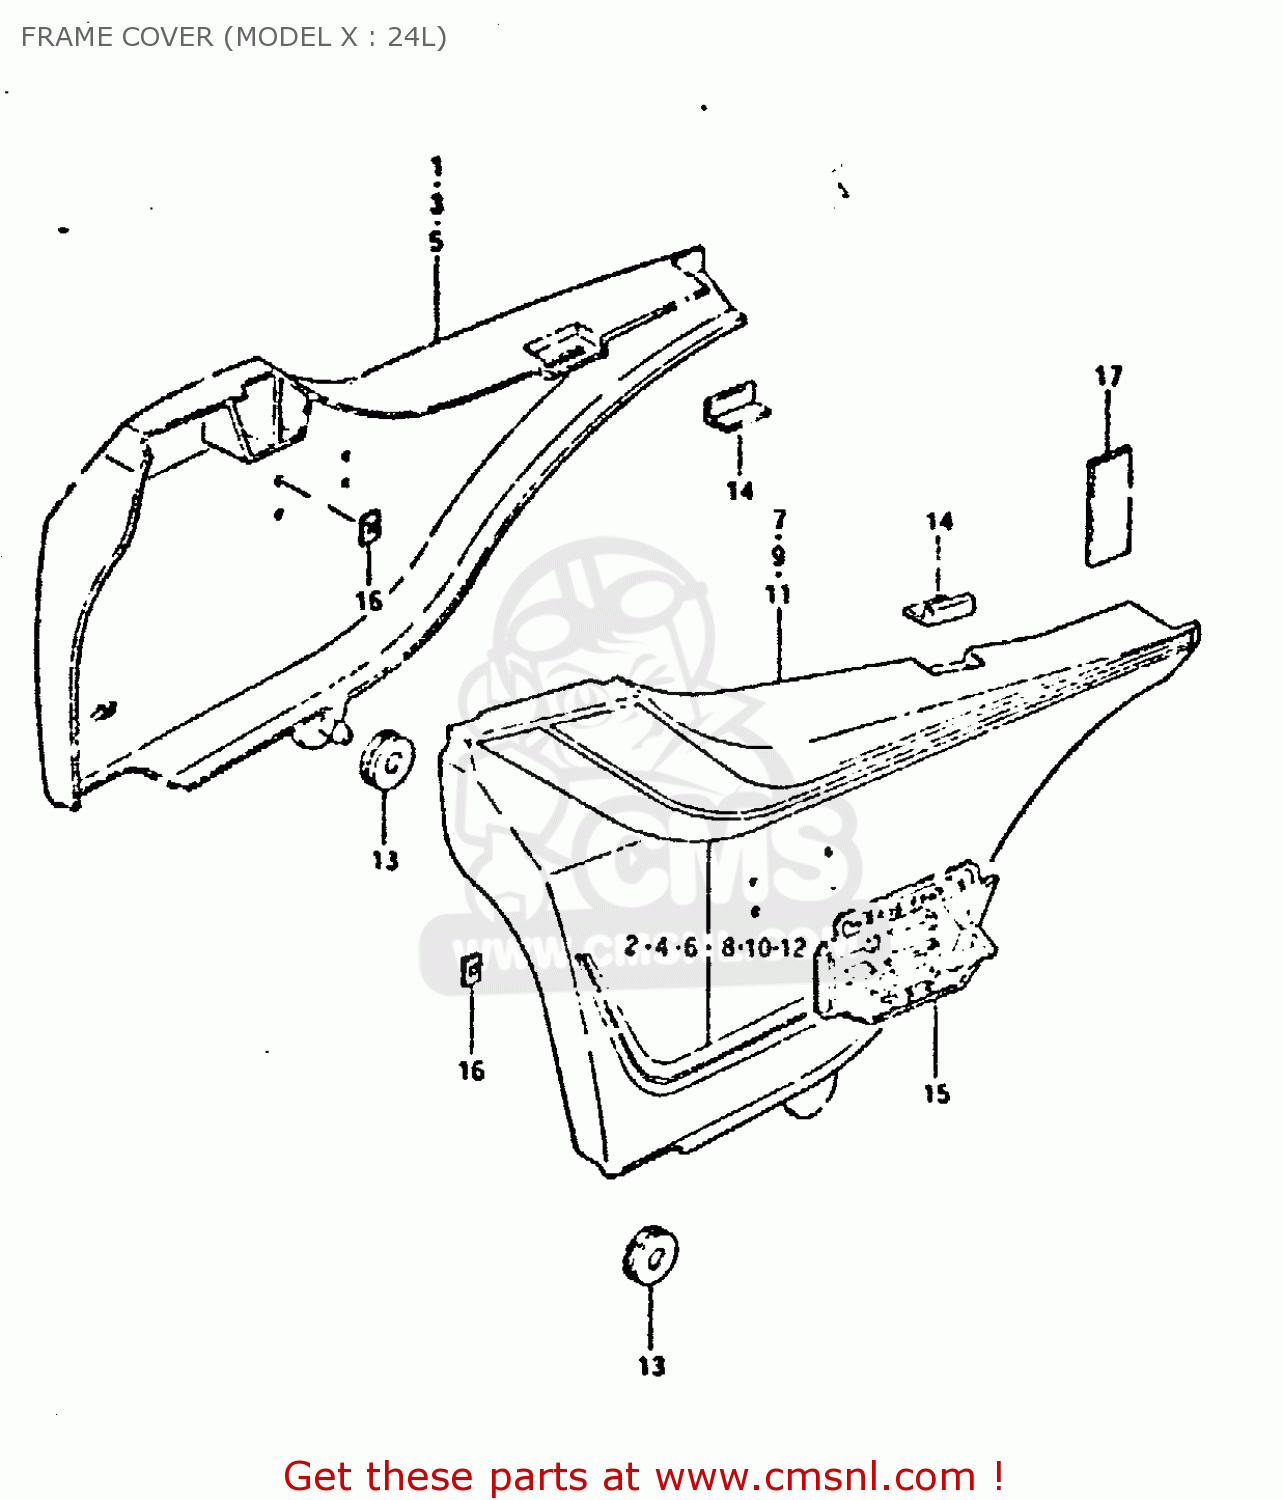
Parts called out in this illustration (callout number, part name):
1	COVER, FRAME RH (BLACK)
2	TAPE, RH
3	COVER, FRAME RH (RED)
4	TAPE, RH
5	COVER, FRAME RH (BLUE)
6	TAPE, RH
7	COVER, FRAME LH (BLACK)
8	TAPE, LH
9	COVER, FRAME LH (RED)
10	TAPE, LH
11	COVER, FRAME LH (BLUE)
12	TAPE, LH
13	CUSHION
14	CUSHION,FRAME COVER
15	EMBLEM,FRAME COVER
16	NUT
17	RUBBER,FRAME COVER
